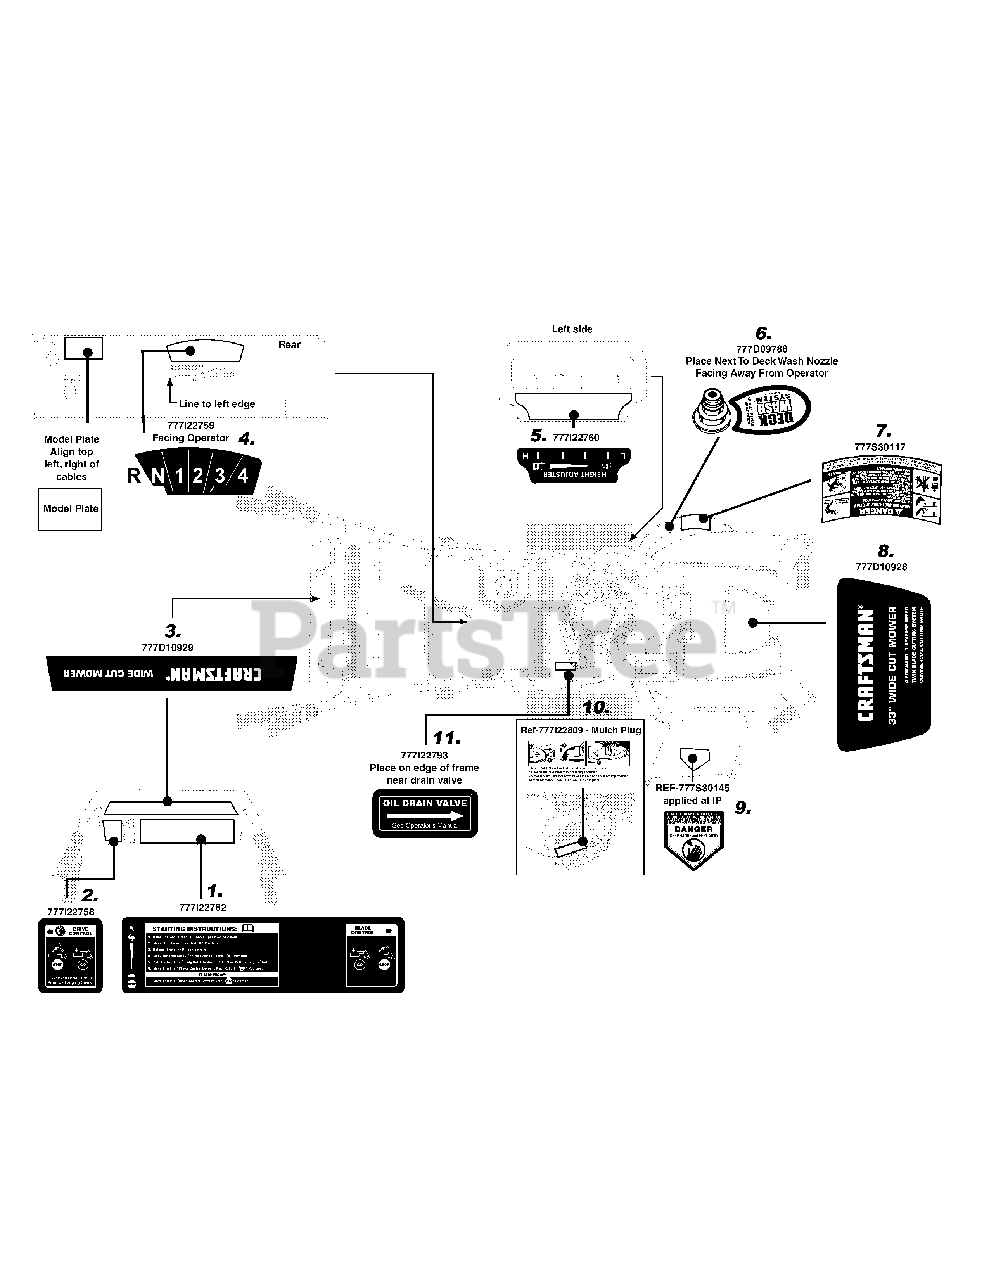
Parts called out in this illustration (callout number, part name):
1	LABEL-BLADE CNTRL/STARTING
2	LABEL-DRIVE CNTRL
3	LABEL-CRAFTSMAN HNDL PN
4	LABEL-SPEED INDICATE
5	LABEL-HEIGHT ADJUST
6	LABEL:RIDER:WHITE
7	LABEL-DANGER
8	LABEL-CRAFTSMAN 33"
9	LABEL
10	LABEL-MULCH PLUG
11	LABEL-OIL DRAIN VLV
